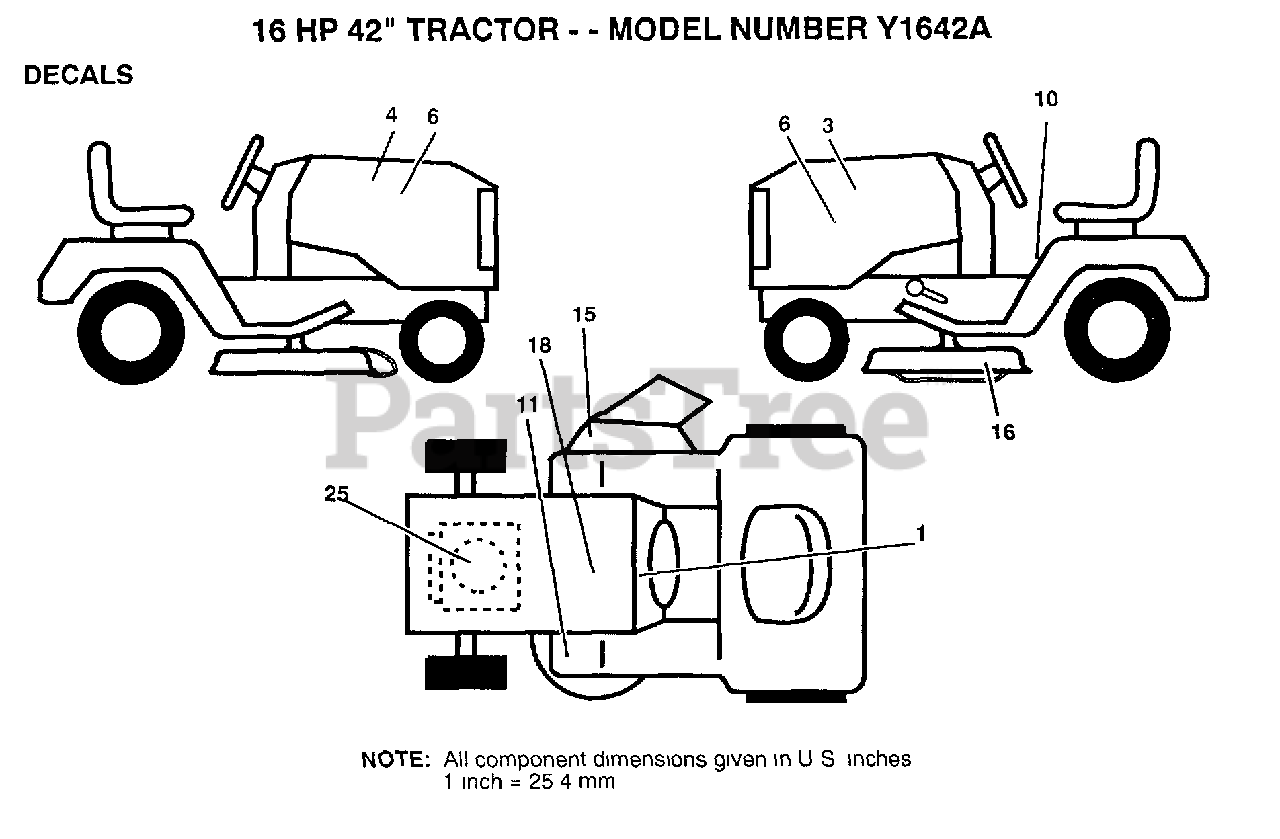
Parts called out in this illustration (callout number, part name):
3	DECAL HOOD LH
10	DECAL CAUTION
11	DECAL T
15	DECAL WARNING
16	DECAL YT
18	DECAL
